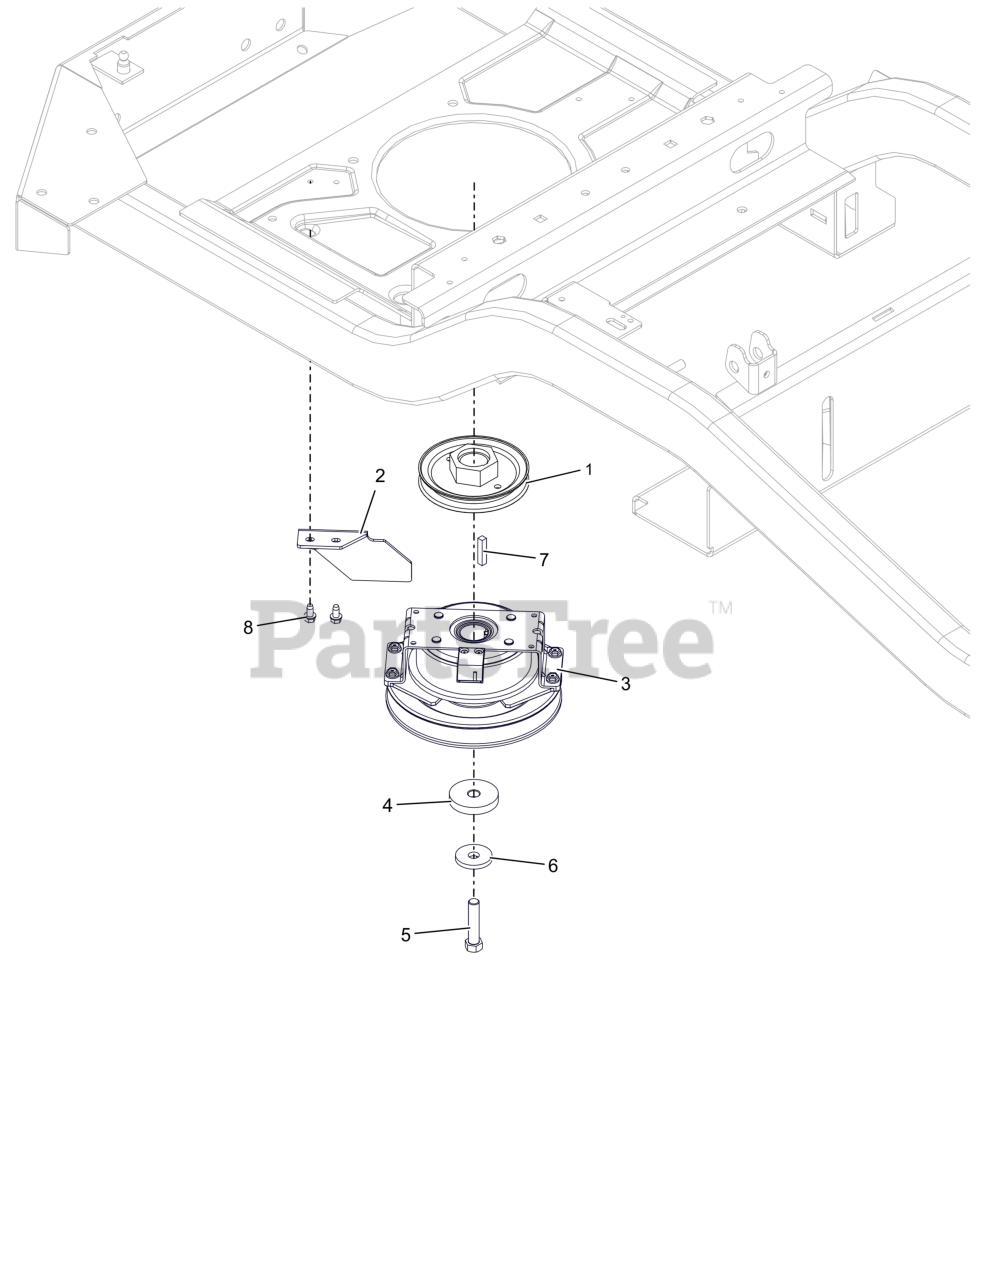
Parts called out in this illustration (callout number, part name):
1	WLDMT,PULLEY-4.50ODX1.127
2	BRKT, CLUTCH STOP HD
3	CLUTCH, OGURA DBLS SPRG 1.13"
4	SPACER, .474/.459X2.00X.350
5	BLT, HEX .44-20X2.00 G8 ZCC NT
6	WASHER, 7/16" SPRING DISK
7	KEY-SQ .25 X 1.25 X .25 SAE
8	SCR-TAP .25-20X.50 HWH ZCC
